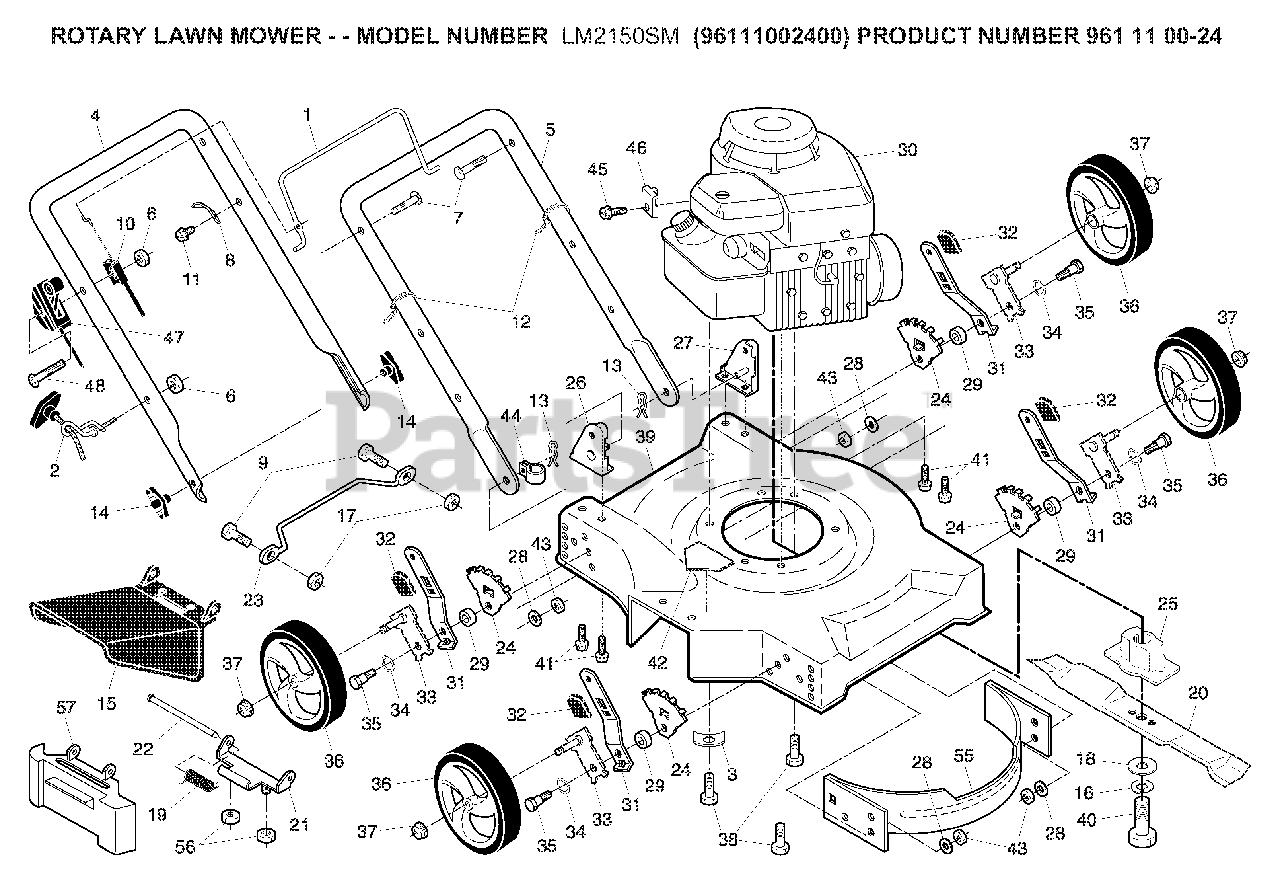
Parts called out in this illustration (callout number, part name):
2	GUIDE.ROPE.STD.BLK.ZIN
4	HANDLE.UPPER.FGD/PUSH.BLACK
6	NUT
7	BOLT, HANDLE 5/16-18X1.75
8	BRACKET UPSTOP
10	CONTROL CABLE
12	TIE GUIDE
13	HAIRPIN COTTER
14	KNOB, DEFLECTOR
16	LOCKWASHER
18	WASHER,HARDEN
20	BLADE.20.MULCH.(50DK,6020MD)
21	HINGE DEFLECTOR
22	HINGE ROD
24	BRACKET.ADJ.WHEEL.5POS.ADS
25	BLADE ADAPTOR
26	HANDLE BRACKET ASM. RH
27	HANDLE BRACKET ASM. LH
28	WASHER
29	SPACER.HEIGHT.ADJUSTER
31	SELECTOR SPRING, FRONT
33	AXLE ARM ASSY.
34	WASHER FLAT
35	SHOULDER BOLT 5/16-18
37	NUT.HEX.FLANGE.3/8-16.LOCKNUT
38	BOLT 3/8-16X1-1/8
40	SCREW, HEX HD 3/8-24 X 1-3/8
41	SCREW 5/16-18
42	DECAL.INTERNATIONL.CUTFINGER
43	NUT.CENTERLOCK.5/16-
44	CLIP.CABLE.BLK
45	SCREW.HEX.HEAD.WASHER.10-16
46	CABLE CLAMP(ENGINE)
47	THROTTLE CONTROL
56	LOCKNUT
